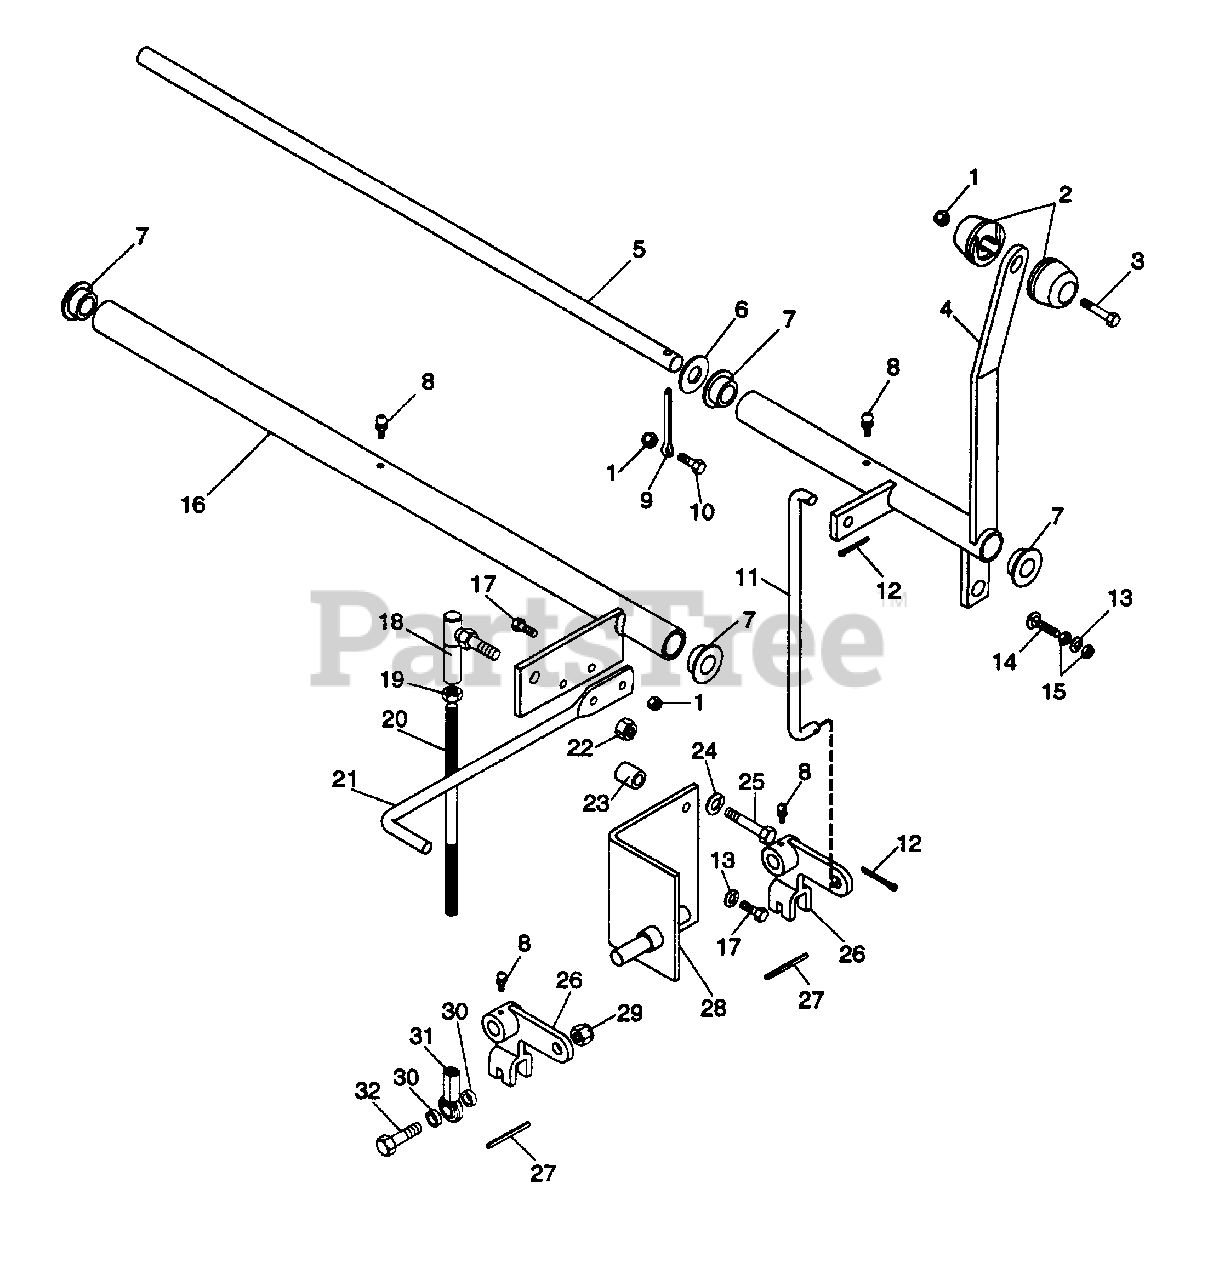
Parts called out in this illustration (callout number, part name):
1	NUT-LK-NYL .250-20 PL
2	KNOB, CONTROL
3	PIN-GRV .250 X 1.25 TP E
4	CNTRL, HI-LO
5	SHFT, CONTROL
6	WSHR-FL-STL .531 X 1.062 X .095
7	BUSH., F .515 X 1.00 X .745 NY
8	FTG, LUBE; .25-28 SELF-THREAD
9	PIN-COTR .250 X 2.00
10	BLT-HEX .25 - 20 X .875
11	ROD, HI-LO
12	PIN-COTR .09 X .75 PL
13	WSHR-LOCK .250 REG.
14	SCR-MCH .25-20 X 1.25 HSHD
15	NUT-HEX .250-20 ZC
16	WLDMT, DIFF LOCK CONTROL
17	BLT-HEX .25-20 X .75 PL GR 5
18	JT, STEERING BALL
19	NUT-HEX .375-24 ZC
20	ROD, LOCK CONTROL
21	BAR, FOOT
22	NUT-LK-NYL .375-24 W/INST
23	BSHG-SLV .407 X .625 X .750 PL
24	WSHR-LOCK .313 X .078 PL
25	BLT-HEX .31-18 X 2.00 PL GR 5
26	LEVER, HI-LO
27	PIN, SPRING, .250 X 1.000
28	BRKT, SHIFT
29	NUT-LK-NYL .375-16 PL
30	BSHG .383 X .50 X .165
31	ROD END, SPHERICAL BRG
32	BLT-HEX .38 - 16 X 1.50 PL GR 5
